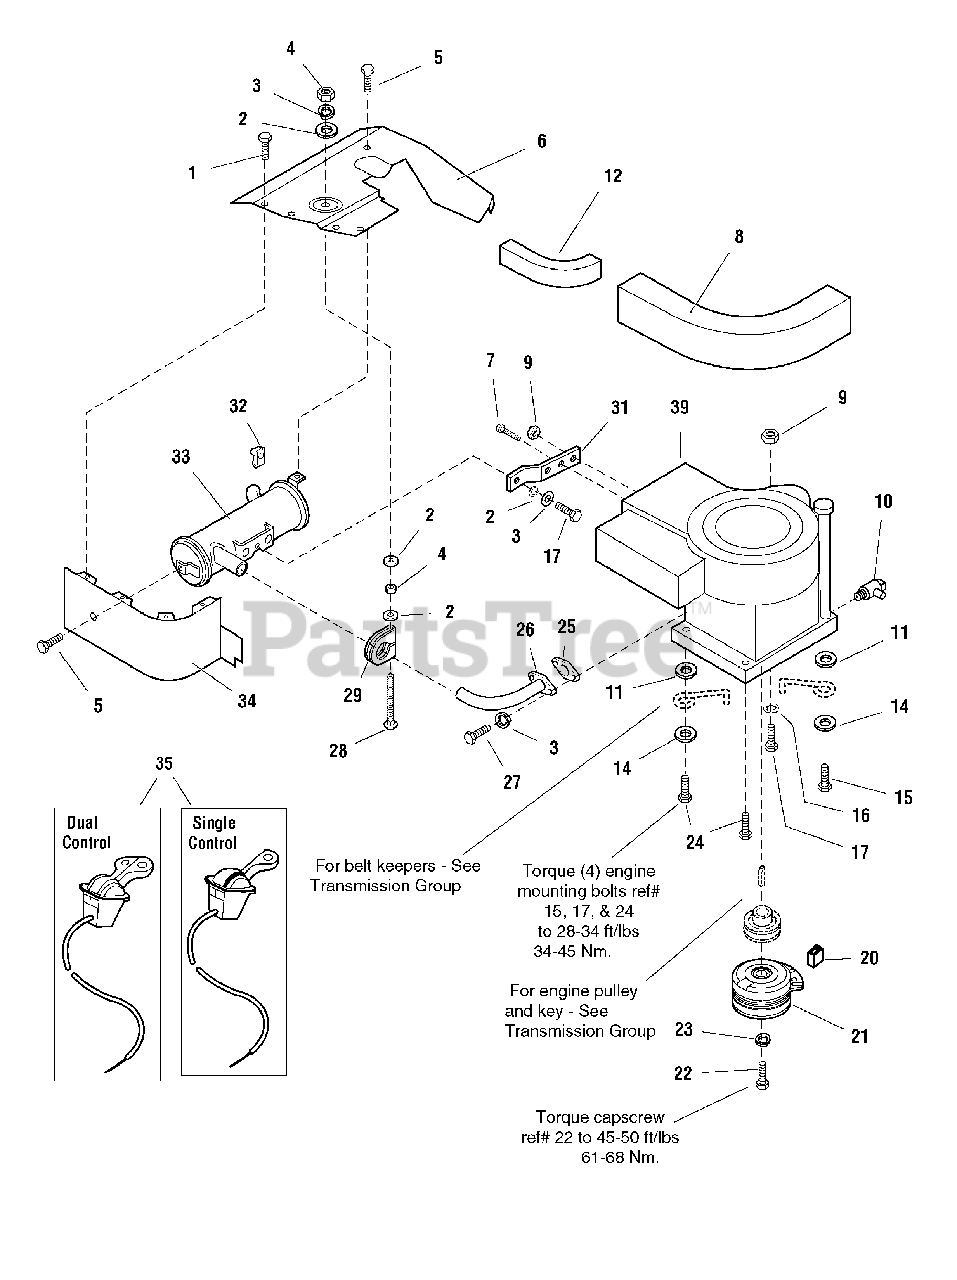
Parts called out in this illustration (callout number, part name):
1	SCREW, Thread Forming, #10-16 x 1/2
2	WASHER, .34
3	LOCKWASHER, 5/16
4	NUT, Hex, 5/16-18
5	CAPSCREW, Hex Head, Taptite, 5/16-18 x 1/2
6	DUCT, R.H., Top
7	SCREW, Taptite, 1/4-20 x .88
8	SEAL, Air Inlet
9	NUT, Flange, Whizlock, 5/16-18
10	VALVE, Shut-Off
11	WASHER, Plain
12	EDGING, Seal
14	WASHER, 3/8
15	CAPSCREW, Taptite, 3/8-16 x 2
16	PUSH NUT, 5/16-18
17	CAPSCREW, Hex, Whizlock, Flange, 5/16-18 x 1-1/2
20	SLEEVE, Clutch Anchor
21	CLUTCH, Electric, Kit
22	CAPSCREW, Hex Head, 7/16-20 x 2-1/2
23	LOCKWASHER, 7/16
24	CAPSCREW, Taptite, 3/8-16 x 1-1/2
25	GASKET, Muffler
26	PIPE, Exhaust
27	CAPSCREW, Socket Head, 5/16-18 x 3/4
28	CARRIAGE BOLT, 5/16-18 x 3-1/4
29	CLAMP, Muffler
31	SUPPORT, Muffler
32	NUT, Speed, Lug Type, 5/16-18
33	MUFFLER ASSEMBLY
34	DUCT, Bottom
35	THROTTLE CONTROL, Dual (Export Only)
35	THROTTLE CONTROL, Single
39	* ENGINE, Briggs & Straton, 13HP, Mod. 21A907-0131-E1
